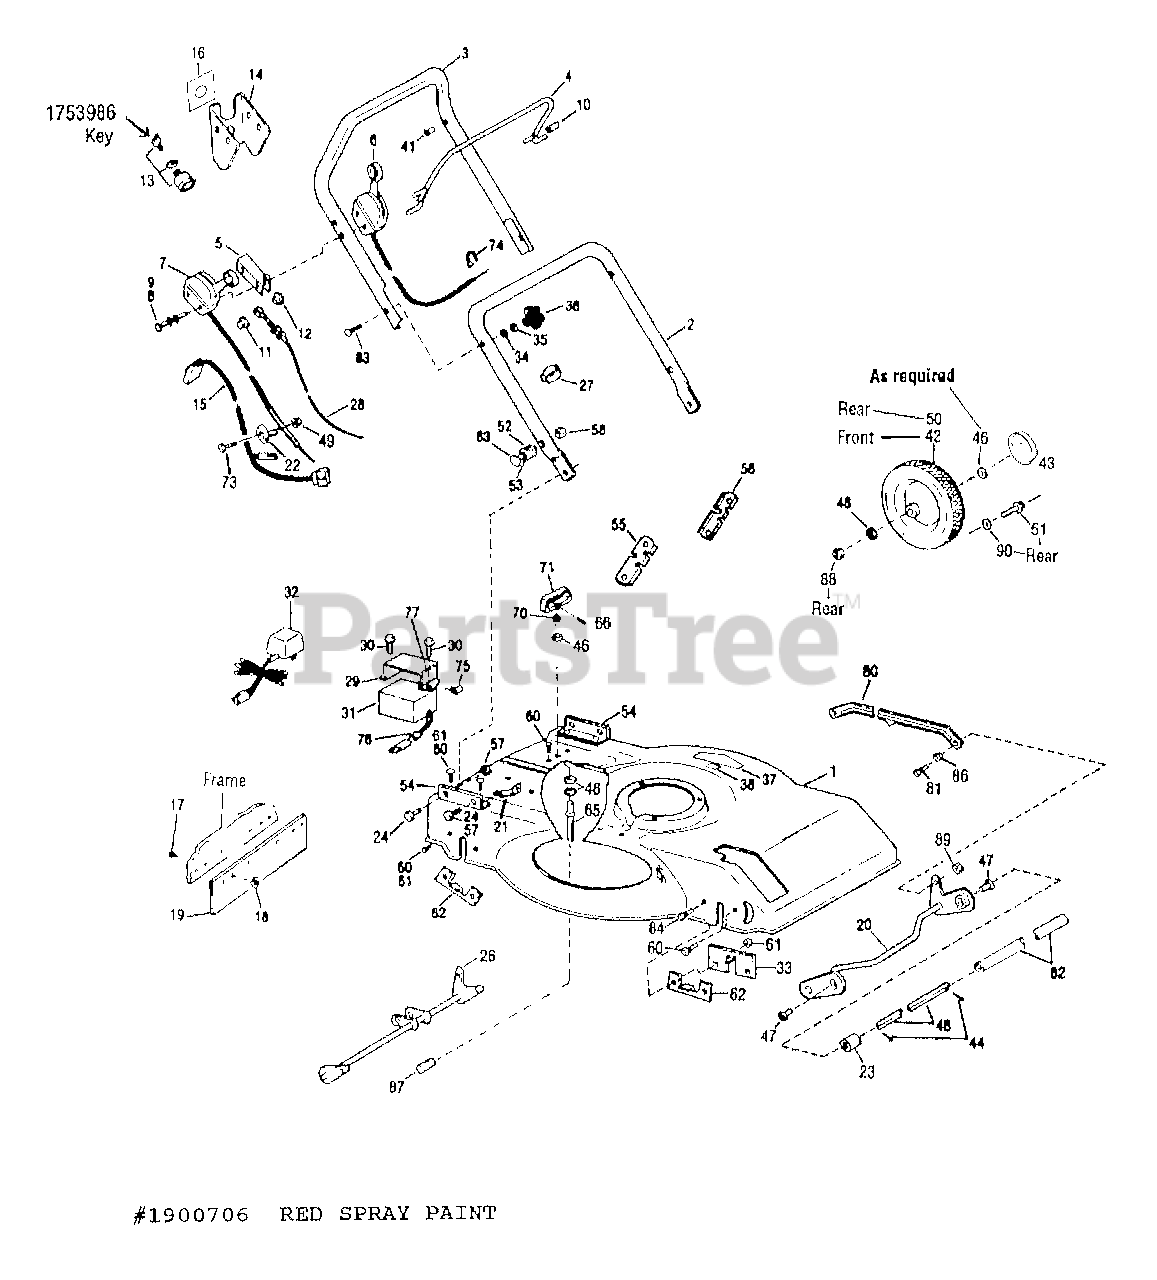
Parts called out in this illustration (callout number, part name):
1	ASSM-BASE W/DECAL 22"MLCH
2	HANDLE-LOWER - BLACK
3	HANDLE-UPPER - BLACK
4	ASSM-BAIL ENGINE CONTROL - BLACK
5	SUPPORT-CONTROL
6	CONTROL-THROTTLE
7	CLUTCH-CONTROL
8	SCR-HH SEMS
8	SCR-HHS {8656R/RS}
9	NUT W/LKWASHER 10-24 ZP
10	GRIP-HANDLE
11	CAP-PUSH ON .312 DIA
12	RING-GRIP EXT .312 ID
13	SWITCH-EL IGNITION {8656R/RS}
13	KEY-IGNITION
14	SUPPORT-SWITCH {8656R/RS}
15	HARNESS-WIRE {8656R/RS}
16	DECAL-ELEC START {8656R/RS}
17	RIVET-POP
18	WASHER-.88X.2X.059
19	SHIELD-DEFLECTOR
20	KIT-AXLE ASM FRNT
22	CLAMP-POWDEN WIRE
23	BUSHING-AXLE
24	SCR-HH 3/8-16X.75 G5 ZP
26	ASSM-AXLE REAR
27	CLIP-WIRE
28	CABLE-ENGINE BRAKE {8655R/RS, 8656R/RS}
29	CLAMP-BATTERY {8656}
30	SCR-FLANGE 1/4-20X3/4 GR5
31	KIT-BATTERY REPLACE {8656R/RS}
32	CHARGER-ELEC BATTERY {8656R/RS}
33	PLATE-DOUBLER
34	WASHER-LK .312 ZP
35	WASHER-FLAT 5/16 SAE
37	DECAL-OPEI CAUTION {8656R/RS}
38	DECAL-HT INDICATOR
41	BEARING-FLANGED
42	TIRE/WHEEL FRONT F/TB MULCH MW
43	CAP-HUB T/B MULCHERS
44	PIN-COTTER .125 X .75 ZP
46	WASHER-FLAT .88X.5X.06 ZP
47	BEARING-AXLE
48	AXLE-DRIVE
49	NUT-HFLK 10-24
50	TIRE/WHEEL (REAR)
51	SCR-SHLDR 3/8-16
52	SPRING-COMPRESSION
53	SPACER
54	BRKT-HANDLEBAR
55	SUPPORT-HANDLE RH
56	SUPPORT-HANDLE LH
57	NUT-LOCK 3/8-16
58	NUT-HFT/LK
60	SCR-CARR 5/16-18X.62 G2 ZP
61	NUT-HFLK 5/16-18 ZP
62	BRACKET-AXLE
66	PIN-ROLL .188X1.0
70	SPACER-HANDLE
71	HANDLE-HEIGHT ADJ
73	SCR-HW M10-24X.88 EXTTOOTH
74	TIE-CABLE NYLON BLACK {8646R/RS}
75	CLAMP-WIRE {8656R/RS}
76	DECAL-CHARGING INST {8656R/RS}
77	PAD-BATTERY {8656R/RS}
80	LINK-HEIGHT ADJUST
81	SCR-SHOULDER
82	TUBING-PLASTIC
83	SCR-CURVED HD 5/16-18X2.0
84	SCR-TRUSS HD 5/16-18X.62
86	BEARING-NYLINER
87	PIVOT-ADJUSTING SCR
88	NUT-HFLK 3/8-16 ZP
89	NUT-HEX JAM 5/16-18
90	WASHER-1.12X.378X.125
